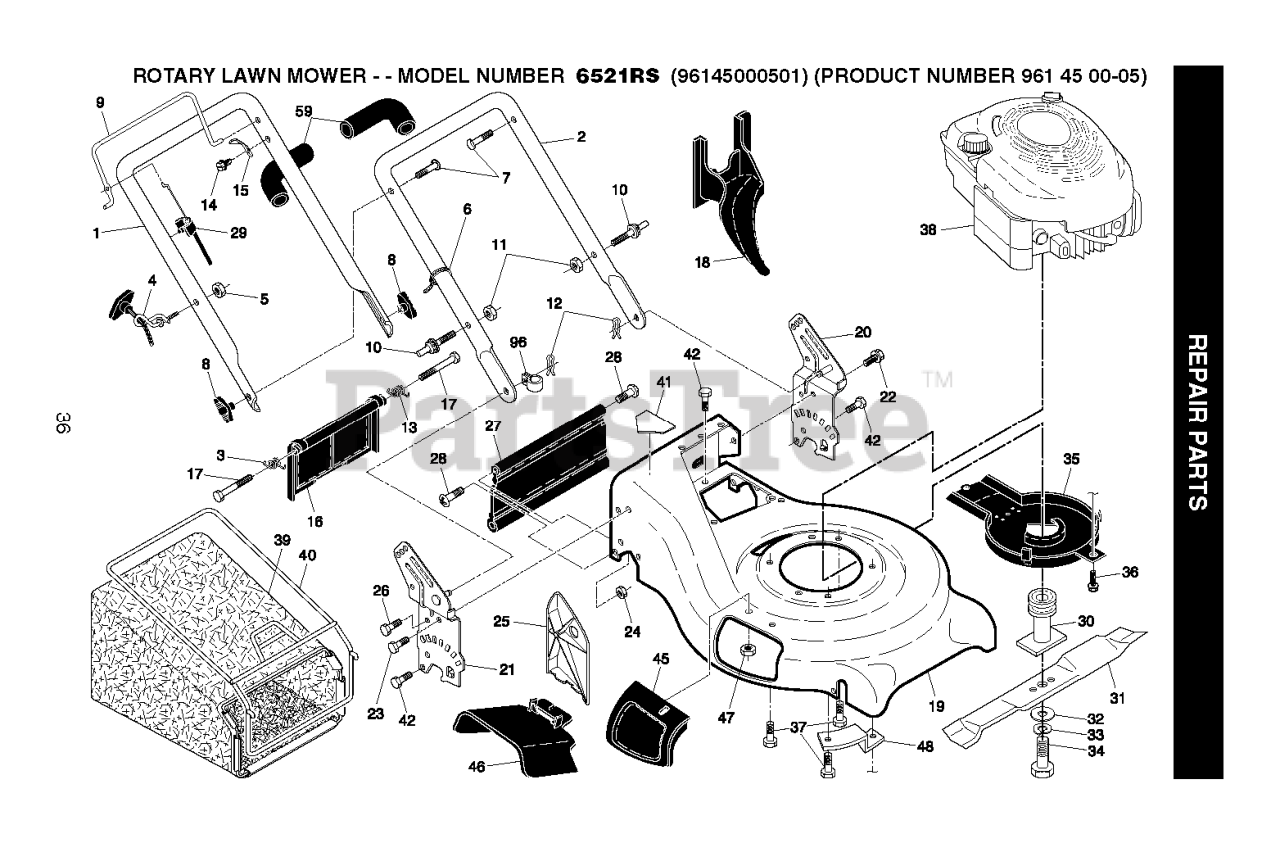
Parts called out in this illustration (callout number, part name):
1	HANDLE.ASM.UP.OFF/EZ.CR.W/GRIP
2	HANDLE.LOWER.21.GREY
3	SPRING.RH.REAR.DOOR.21.RWGD
4	RB GUIDE.ROPE.STD.BLK.ZIN WSL
5	NUT
6	TIE GUIDE
7	BOLT, HANDLE 5/16-18X1.75
8	KNOB.HANDLE.STAR.HUSQ.GRAY
9	BAIL.DSTRT.FL.AW.CREAS.ORANGE
11	NUT.LOCK.5/16-18
12	HAIRPIN COTTER
13	SPRING.LH.REAR.DOOR.21.RWGD
15	BRACKET UPSTOP
16	REAR DOOR ASSEMBLY
18	PLUG.MULCHER.RGD.21.
19	Kit, Housing
20	LH HANDLE BRACKET ASSEMBLY
21	BRKT.HANDLE.ASM.RWGD.21.RT.BLA
22	SELF-TAPPING SCREW 5/16-18X3/4
23	BOLT, HEX HEAD 5/16-18
24	NUT.71038.31-18.HEX.NYLOCK
25	CLIPPING DEFLECTOR
27	SKIRT.21.RWGD.BLACK
28	HINGE SCREW
29	SNAP-ON.ZONE.CABLE.ASS
30	BLADE ADAPTOR / PULLEY
31	BLADE.21.PUSH/RWGD/FWGD
32	WASHER,HARDEN
33	LOCKWASHER
34	SCREW, HEX HD 3/8-24 X 1-3/8
35	DEBRIS SHIELD
36	SCREW.HEX.WSH
37	BOLT 3/8-16X1-1/8
39	GRASSBAG
40	FRAME, GRASSBAG
41	DANGER DECAL
45	MULCHER DOOR ASM.
46	DEFLECTOR, DISCHARGE
48	BRACKET
59	GRIP.HANDLE.FOAM.WIDE.(1 SIDE)
96	CLIP.CABLE.BLK
